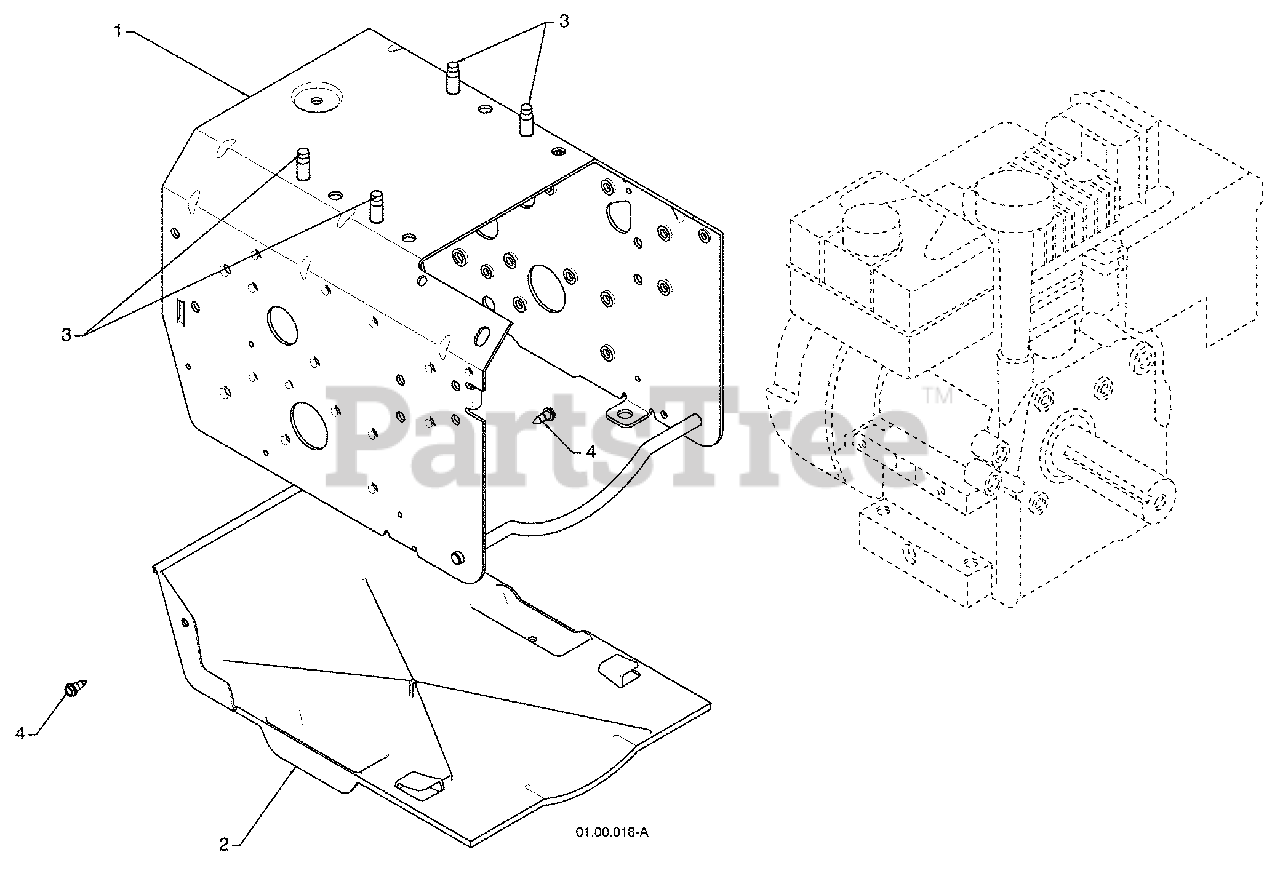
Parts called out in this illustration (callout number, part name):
2	BOTTOM PAN
3	BOLT 3/8-16
4	SCREW 10-24 X .625
